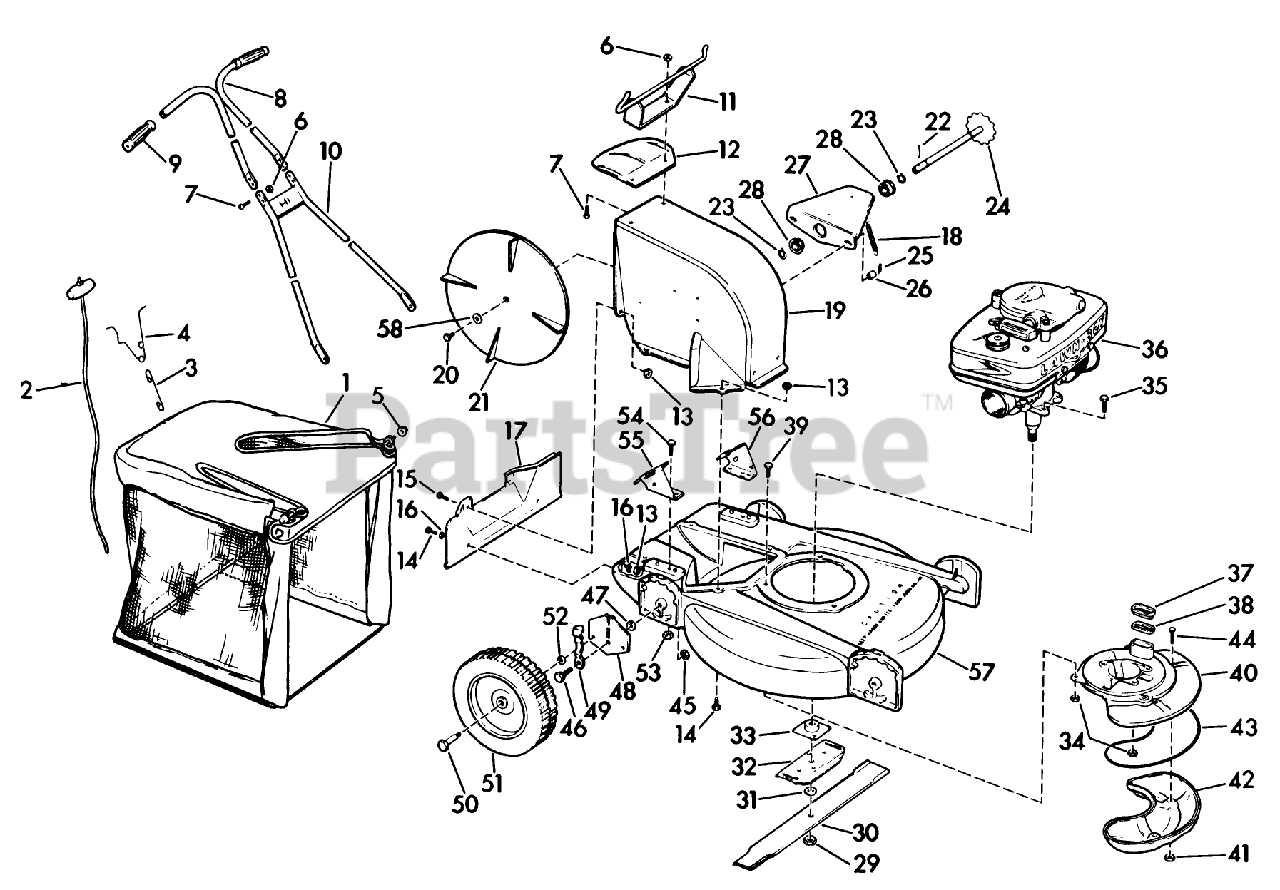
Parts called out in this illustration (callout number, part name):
1	Catcher Assy.-Complete
3	Hook-Catcher
4	Spring-Catcher Rope
6	STOP NUT
12	Deflector-Discharge
17	Bracket-Catcher Stop
18	Spring-Extension
21	Slinger
22	Pin-Spring, Drive Shaft
23	Ring-Retaining, Drive Shaft
26	Sleeve-Rubber
27	Bracket-Drive Shaft
28	Bearing-Ball, Nylon
29	NUT-BLADE
33	PLATE AND COLLAR ASM
41	LOCKNUT E
50	BOLT WHEEL
51	Wheel Assembly-Rear
52	WASHER WROUGHT
57	Housing-21"
